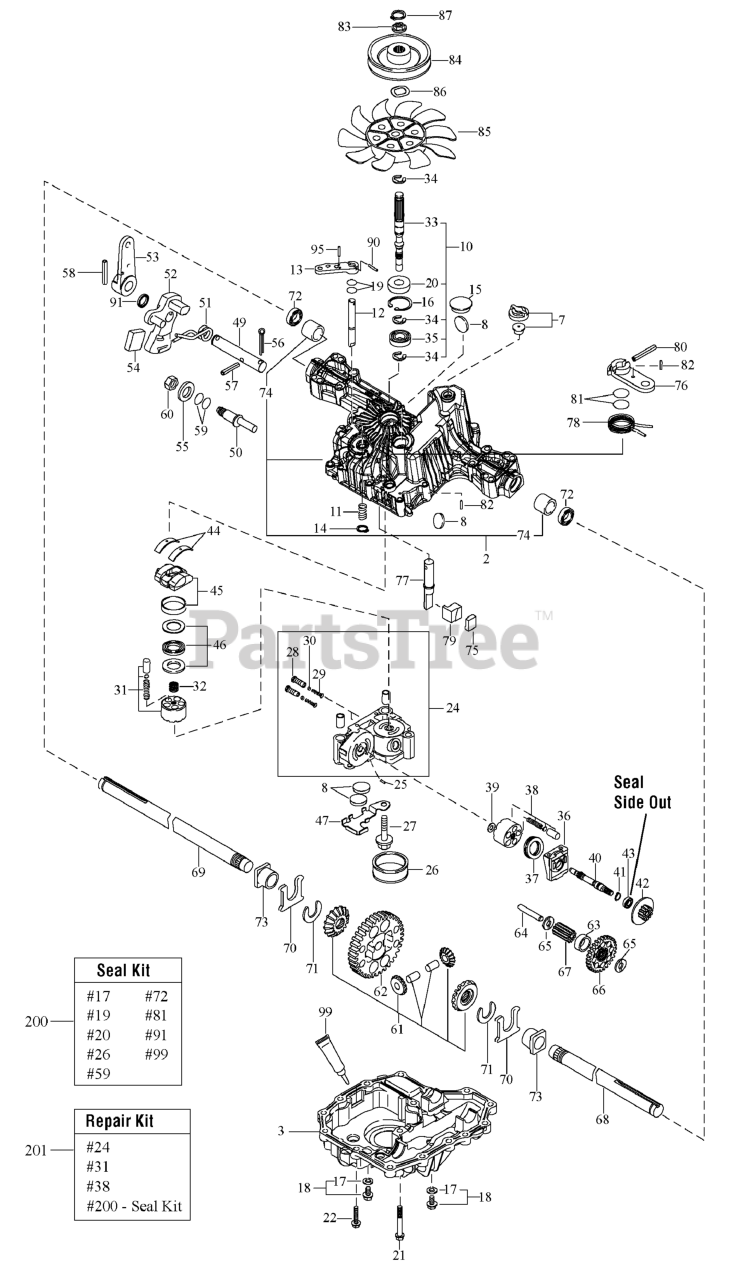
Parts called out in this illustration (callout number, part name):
2	*KIT, Upper Case
3	LOWER CASE
7	VENT VALVE
10	SWITCH (see electrical group)
12	*BYPASS SHAFT
13	LEVER, Bypass
15	SEALING CAP, 30
16	RING, Snap, C 35
17	SEAL WASHER, 8
18	*KIT, Drain Bolt
20	SEAL TC 153507
22	SCREW, Tapping, 8 * 30
24	*KIT, Center Case
25	PIN, 3 * 9.8
29	*IDS SPRING
31	*KIT, Cylinder Block (Pump)
33	PUMP SHAFT
34	E-RING, 15
35	BEARING, 6202C3
36	MOTOR HOUSING
38	*KIT, Cylinder Block (Motor)
39	WASHER, 12 * 24 * 1
40	MOTOR SHAFT
41	RING, Snap, S15
42	BRAKE DISC/MOTOR GEAR (10T)
44	THRUST METAL
45	*SWASH PLATE CMP
46	*THRUST BEARING (PUMP) KIT
47	*MAGNET HOLDER
49	*CONTROL SHAFT
51	*TORSION SPRING
52	*CONTROL ARM A
53	CONTROL LEVER C
54	*JERKY PLATE
58	ROLL PIN 6 * 40
59	O-RING 1A P14
61	SEE HOSE ASSEMBLY
62	SEE HOSE ASSEMBLY
63	*FINAL PINION COLLAR
64	*REDUCTION SHAFT
65	WASHER, 12 * 32 * 3.2
66	REDUCTION GEAR (38T)
68	AXLE SHAFT, Left
69	AXLE SHAFT, Right
70	THRUST WASHER
71	RING, 17
72	SEAL, 19 * 32 * 8
73	BUSHING, 19 * 25
75	BRAKE SHOE
76	BRAKE LEVER
77	SEE HOSE ASSEMBLY
78	*BRAKE RETURN SPRING
79	BRAKE ACTUATOR
80	SPRING PIN, 5 * 32
83	SPLINE COLLAR
84	PULLEY C
85	FAN, White
86	WASHER, Wave
87	RING, Snap
90	SPRING PIN, 3.0A * 20
91	OIL SEAL 16 * 22 * .03
99	SEE HOSE ASSEMBLY
200	SEAL KIT (K46 & T40)
201	*KIT, Repair, K46 (CE,CR)
